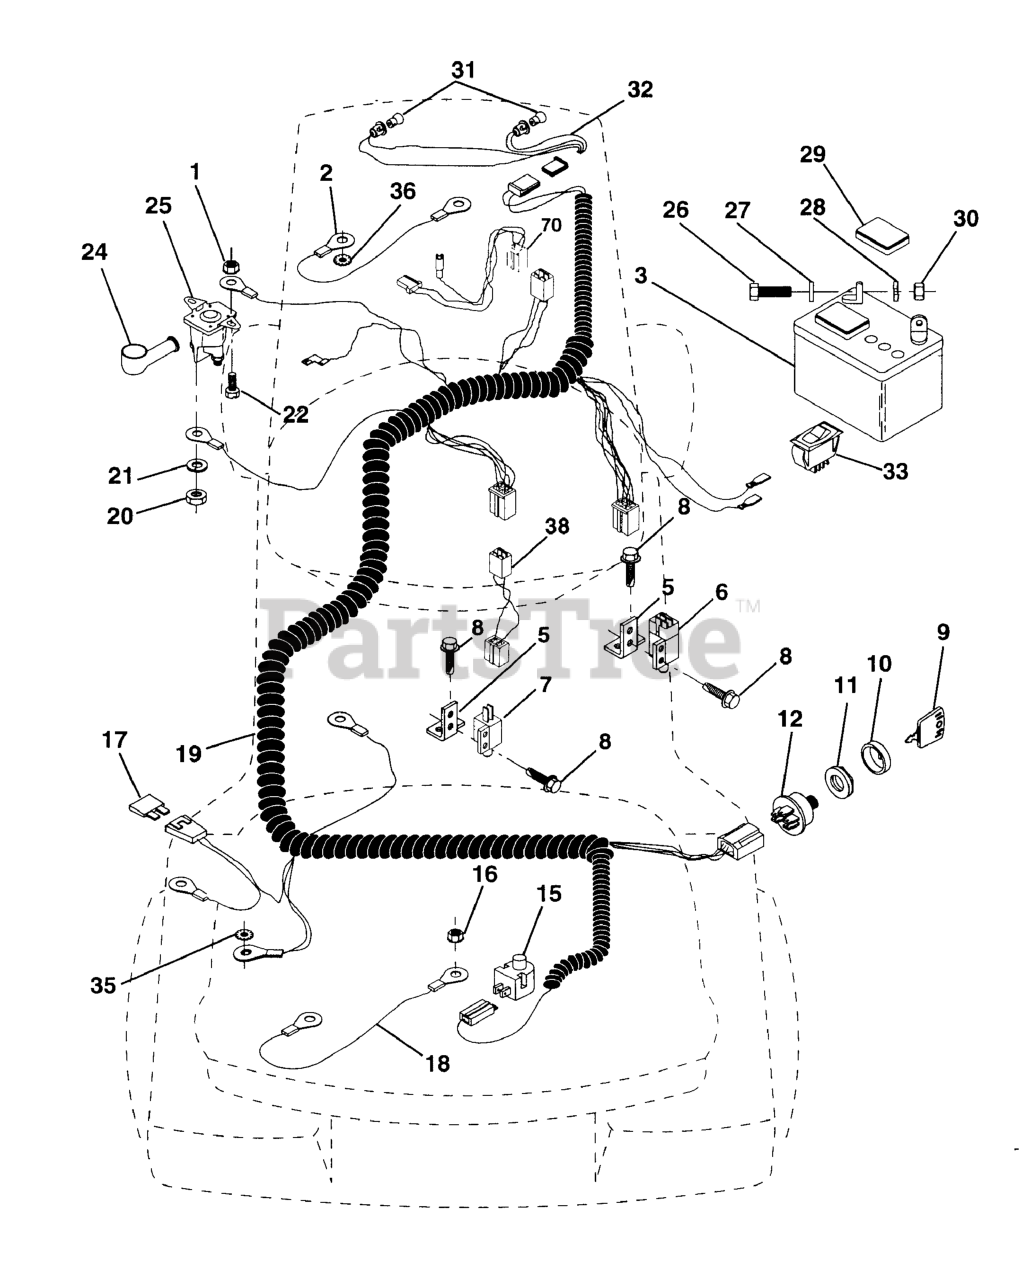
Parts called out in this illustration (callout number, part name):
1	NUT
2	CABLE.BATTERY.6GA.16"RED
3	BATTERY
5	BRACKET LT
6	SWITCH INTERLOCKT
7	SWITCH-INTER. GT
9	KEY-STEEL DELTA
10	COVER KEY IGNITIO
11	NUT, IGNITION
12	IGNITION SWITCH
15	RP.SWITCH.PLUNGER.NC.GRAY
16	NUT
18	CABLE ASSY
19	HARNESS, IGNITON
20	NUT
21	LOCKWASHER
22	BOLT
24	TERMINAL COVER
25	SOLENOID
26	BOLT.HEX.1/4.X.3/4.DICHROMATE
27	WASHER
28	LOCKWASHER
29	CAP BATTERY NLA
30	NUT
32	SOCKET LIGHT HARNESS
35	LOCKWASHER
36	Washer Lock Inter. Tooth 1/4
37	HARNESS, ENGINE
38	ADAPTOR, HARNESS
